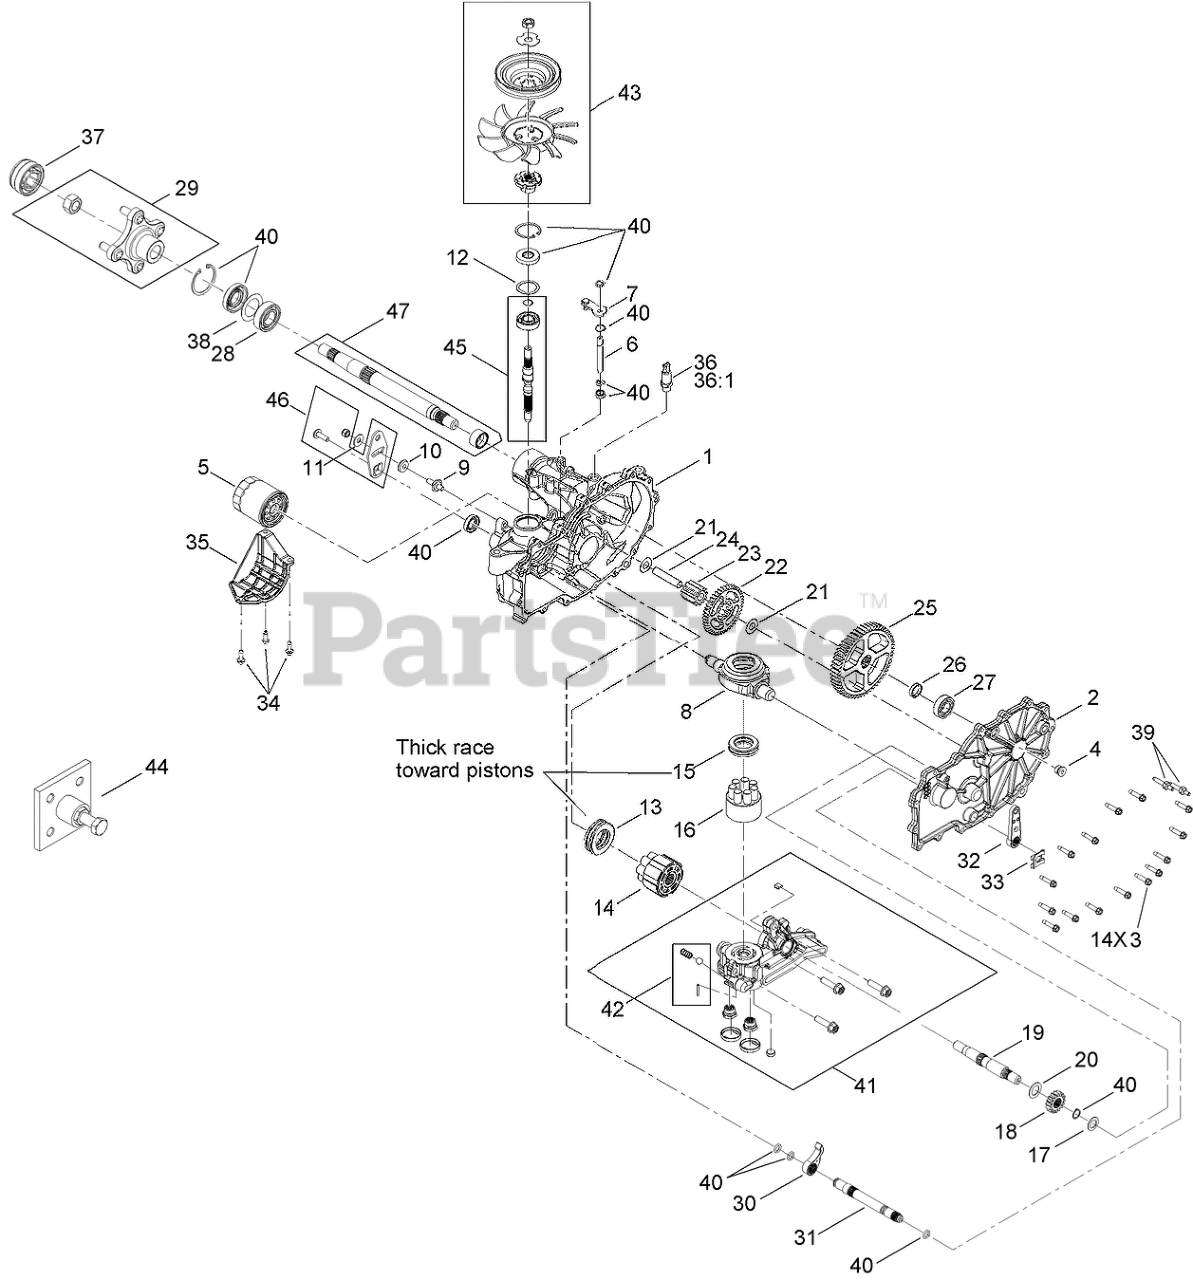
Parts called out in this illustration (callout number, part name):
1	MAIN HOUSING KIT
2	RH HOUSING SIDE KIT
3	SCREW-HHF
4	PLUG-THREAD, STRAIGHT
5	ELEMENT-OIL FILTER, HYD
6	ROD-BYPASS
7	ARM-BYPASS
8	SWASHPLATE-TRUNNION
10	PUCK-FRICTION
11	WASHER
12	SPACER
13	BEARING-THRUST
14	MOTOR CYLINDER BLOCK KIT
15	BEARING-THRUST
16	PUMP BLOCK ASM
17	WASHER-FLAT
18	GEAR-16T
19	SHAFT-MOTOR
20	WASHER
21	WASHER
22	GEAR-43T
23	GEAR-11T
24	PIN-JACKSHAFT
25	GEAR-54T
26	SPACER
27	BEARING-BALL
28	BEARING-BALL
29	HUB KIT
30	PAWL-BRAKE
31	SHAFT-BRAKE, INBOARD
32	HANDLE-BRAKE
33	CLIP-RETAINING
35	GUARD-FILTER, RH
36	ADAPTER-STRAIGHT
36:1	O-Ring
37	COVER-NUT, AXLE
38	SPACER
40	SEAL KIT
41	RH CENTER SECTION KIT
42	CHARGE RELIEF KIT
43	FAN PULLEY KIT
44	PULLER-HUB, 4 BOLT
45	INPUT SHAFT KIT
46	CONTROL ARM KIT
47	AXLE SHAFT KIT
